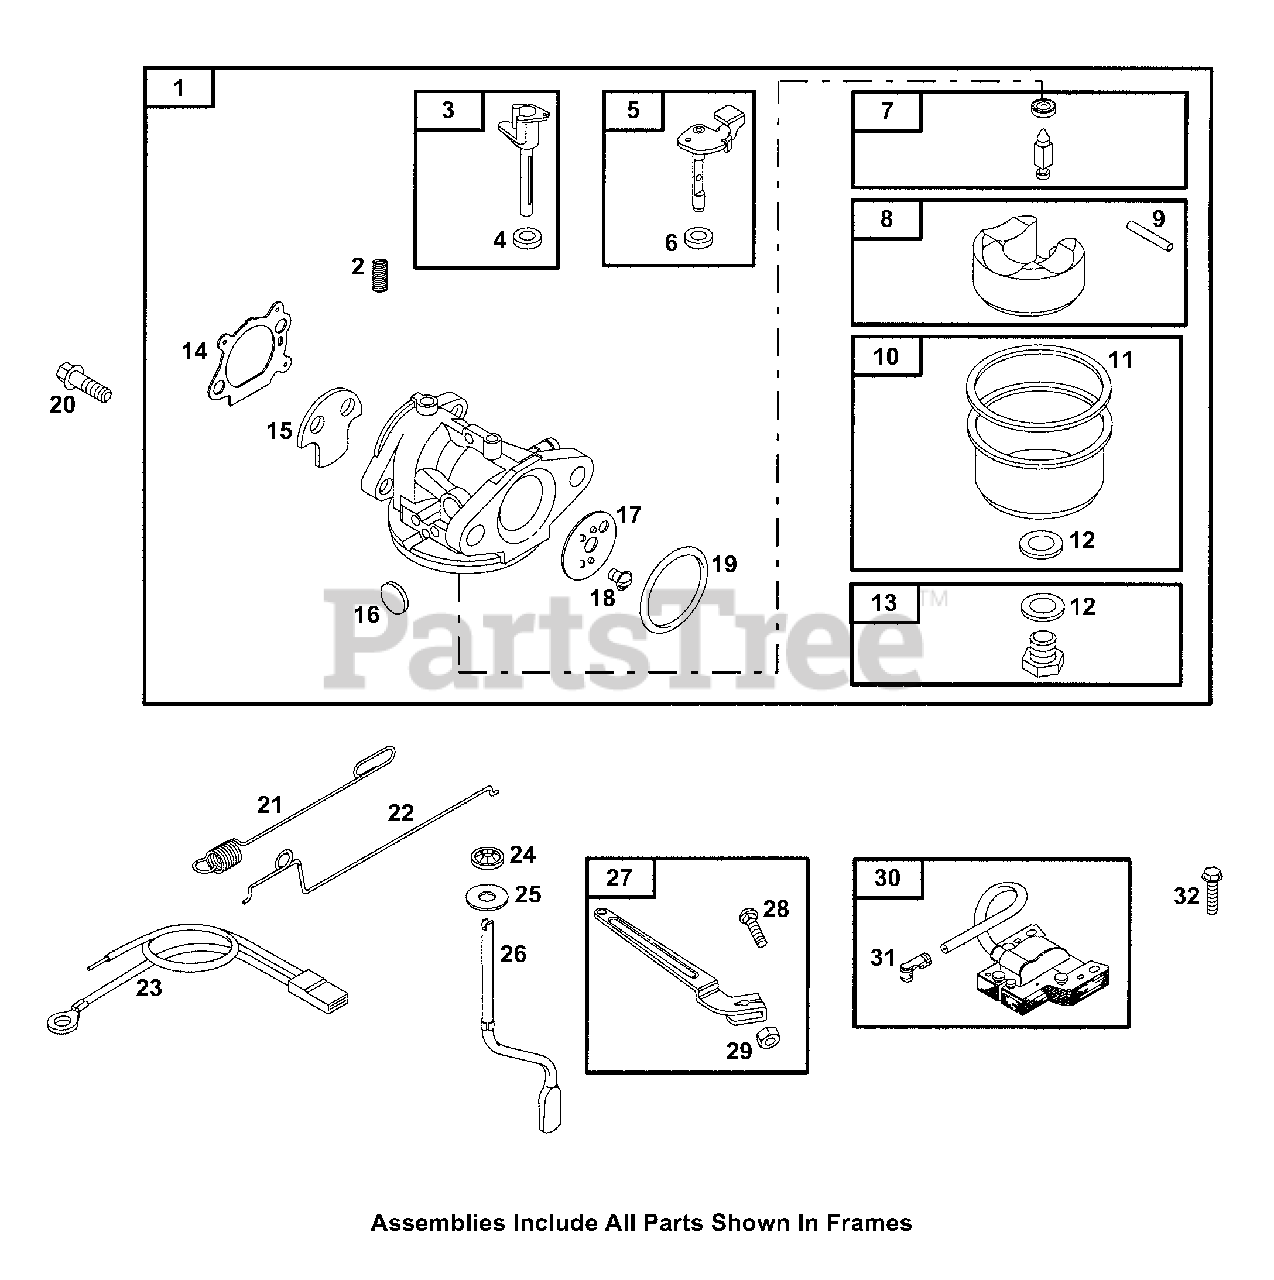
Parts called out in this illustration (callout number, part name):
1	Carburetor
2	Detent Spring
3	Choke Shaft
4	Choke Shaft Seal
5	Throttle Shaft
6	Throttle Shaft Seal
7	Needle/Seat Kit
8	Carburetor Float
9	Float Hinge Pin
10	Float Bowl
11	Float Bowl Gasket
12	Sealing Washer
13	Main Jet (Standard)
14	Air Cleaner Gasket
15	Choke Valve
16	Welch Plug
17	Throttle Valve
18	Screw (Throttle Valve)
19	O-Ring Seal (Intake Manifold)
20	Screw (Carburetor)
21	Governor Spring
22	Mechanical Governor Link
24	Retainer Governor Shaft
25	Washer (Governor Crank)
26	Governor Crank
27	Governor Control Lever
28	Bolt (Governor Control Lever)
29	Nut (Governor Control Lever)
30	Magneto Armature
31	Sparkplug Terminal
32	Screw (Magneto Armature)
